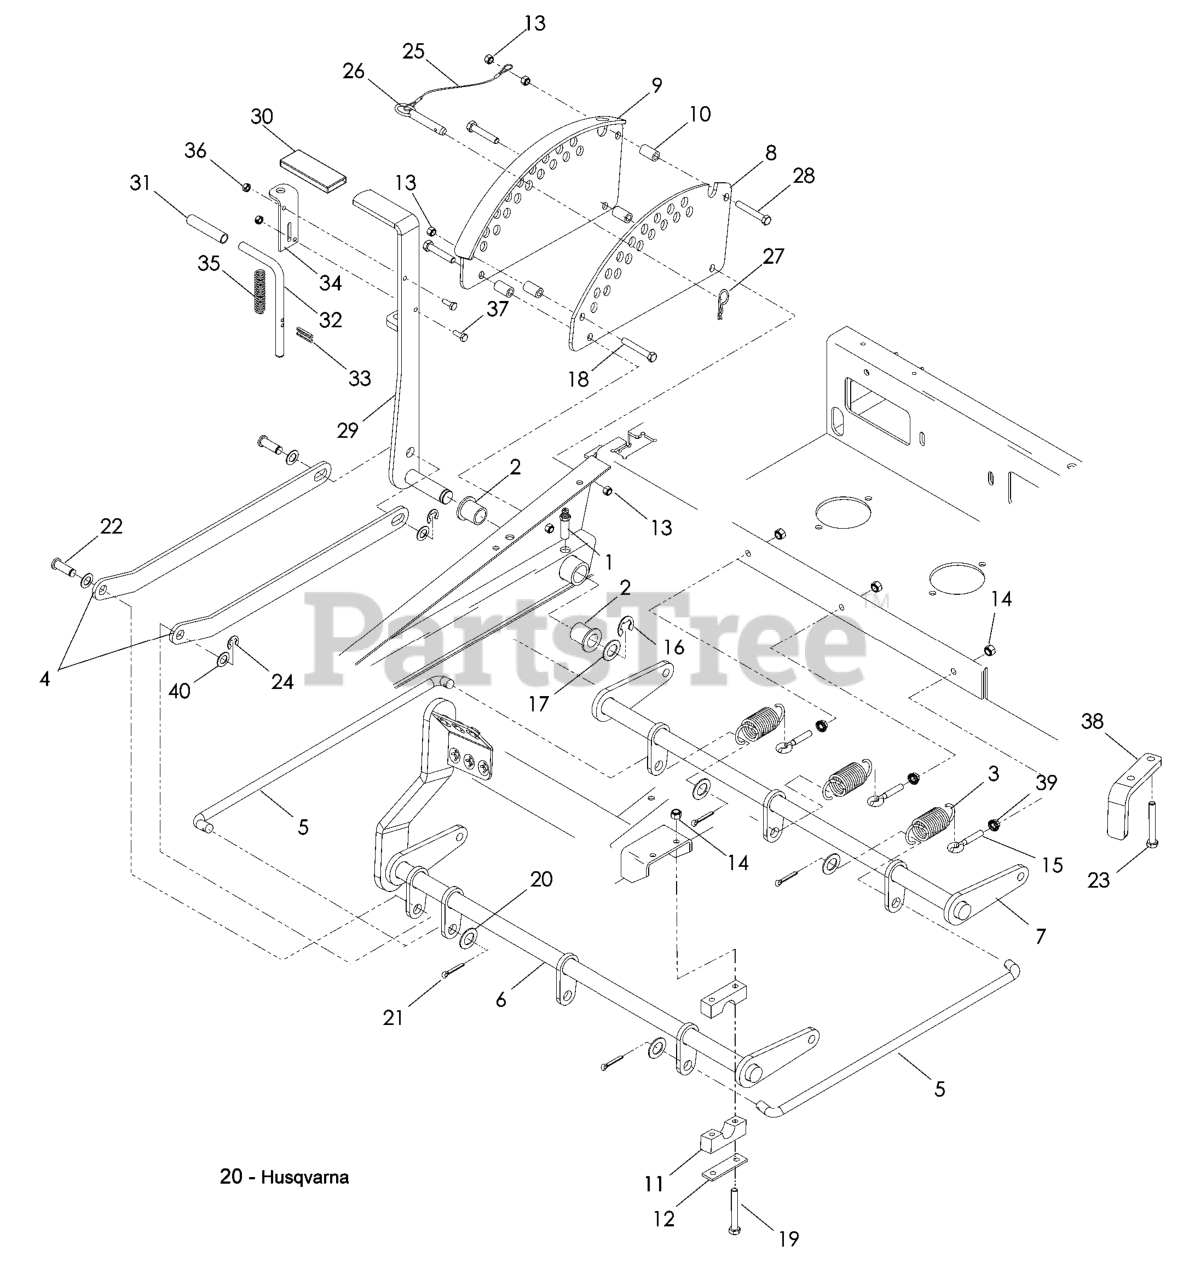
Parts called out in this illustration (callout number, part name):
1	GREASE ZERK LONG
2	BUSHING, FLANGED
3	DECK LIFT SPRING
4	LIFT LINKAGE,PAINTED
5	CONNECTING LINK
6	LIFT SHAFT ASM, FRONT
7	SHAFT LIFT REAR
8	ADJ. PLATE PAINTED
9	ADJ. PLATE WLDMNT
10	DECK LIFT SPACER
11	PILLOW BLOCK
12	REINFORCEMENT BAR
13	NUT 3/8-16 NYLOC
14	NUT 5/16 NYLOC
15	EYEBOLT, RH
16	E-RING 7/8
17	BSHG .875 X 1.375 X .074 ZD
18	HCS 3/8C X 2 1/2
19	HCS 5/16C X 2-3/4
20	WASHER 5/8 FLAT
21	COTTER PIN
22	CLEVIS PIN
23	BOLT 3/8-16 X 1.0
24	E-RING 5/8
27	HAIRPIN #4
28	SCREW 3/8C X 2 3/4 HEX CAP
29	LIFT LEVER WELDMENT
34	PIN MT, UPPER
36	NUT 1/4C CENTER LOCK
37	HCS 1/4C X 3/4 HCS
39	NUT 5/16C WHIZ
40	BUSHING
